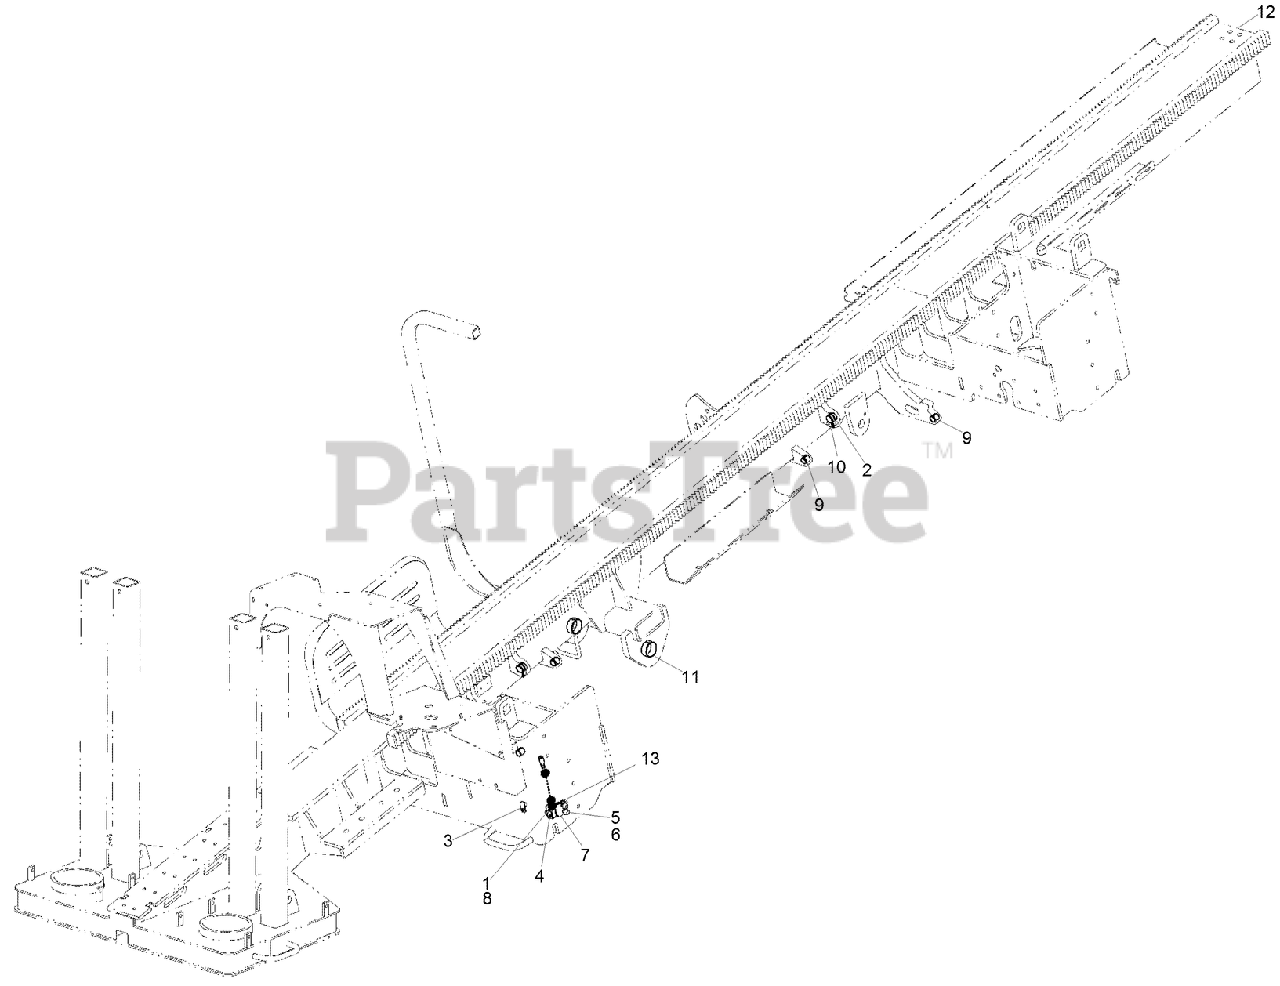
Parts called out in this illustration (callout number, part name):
1	NUT - KEPS Ext T Wshr #6 - 32 UNC ZP
2	FITTING-Lube 1/4-28 Tpr SAE-LT .54 Long
3	CLAMP - Insul, 12.7mm 3/8 in Bolt ZND
4	SWITCH-NEUTRAL START
5	NUT-FLANGE, NYLOCK
6	SCREW-HHF
7	SPACER-SWITCH
8	BOLT-U, SWITCH MTG (H435814)
9	BUSHING-SPRING
10	SPRING BUSHING - 1.00 ID x 1.25 OD x 1.00 Long
11	SPRING BUSHING - 2.00 ID x 2.25 OD x 1.00 Long
12	WELDMENT - Thrust Frame
13	PLATE - Switch Mount
